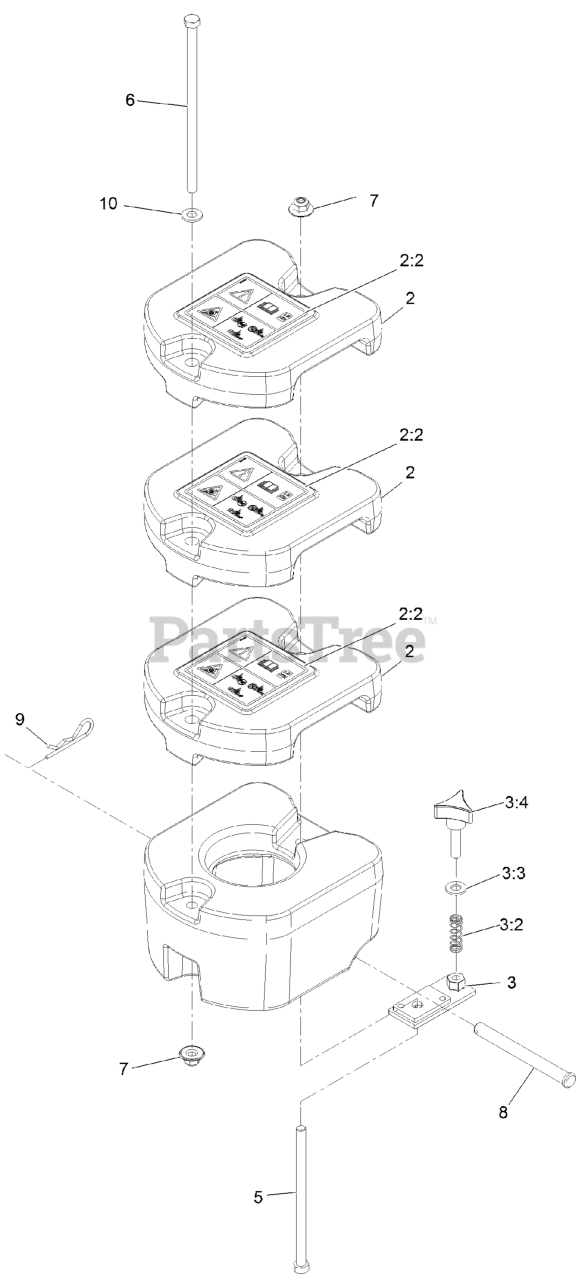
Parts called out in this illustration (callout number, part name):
2	WEIGHT-20LB
2:2	DECAL-WARNING, TRACTION
3	CASTER WEIGHT BRACKET ASM
3:3	WASHER-FLAT
5	SCREW-HH
6	SCREW-HH
7	Nut-Nyloc 3/8-16 Flg
8	PIN-CLEVIS
9	PIN-COTTER
10	WASHER-FLAT
